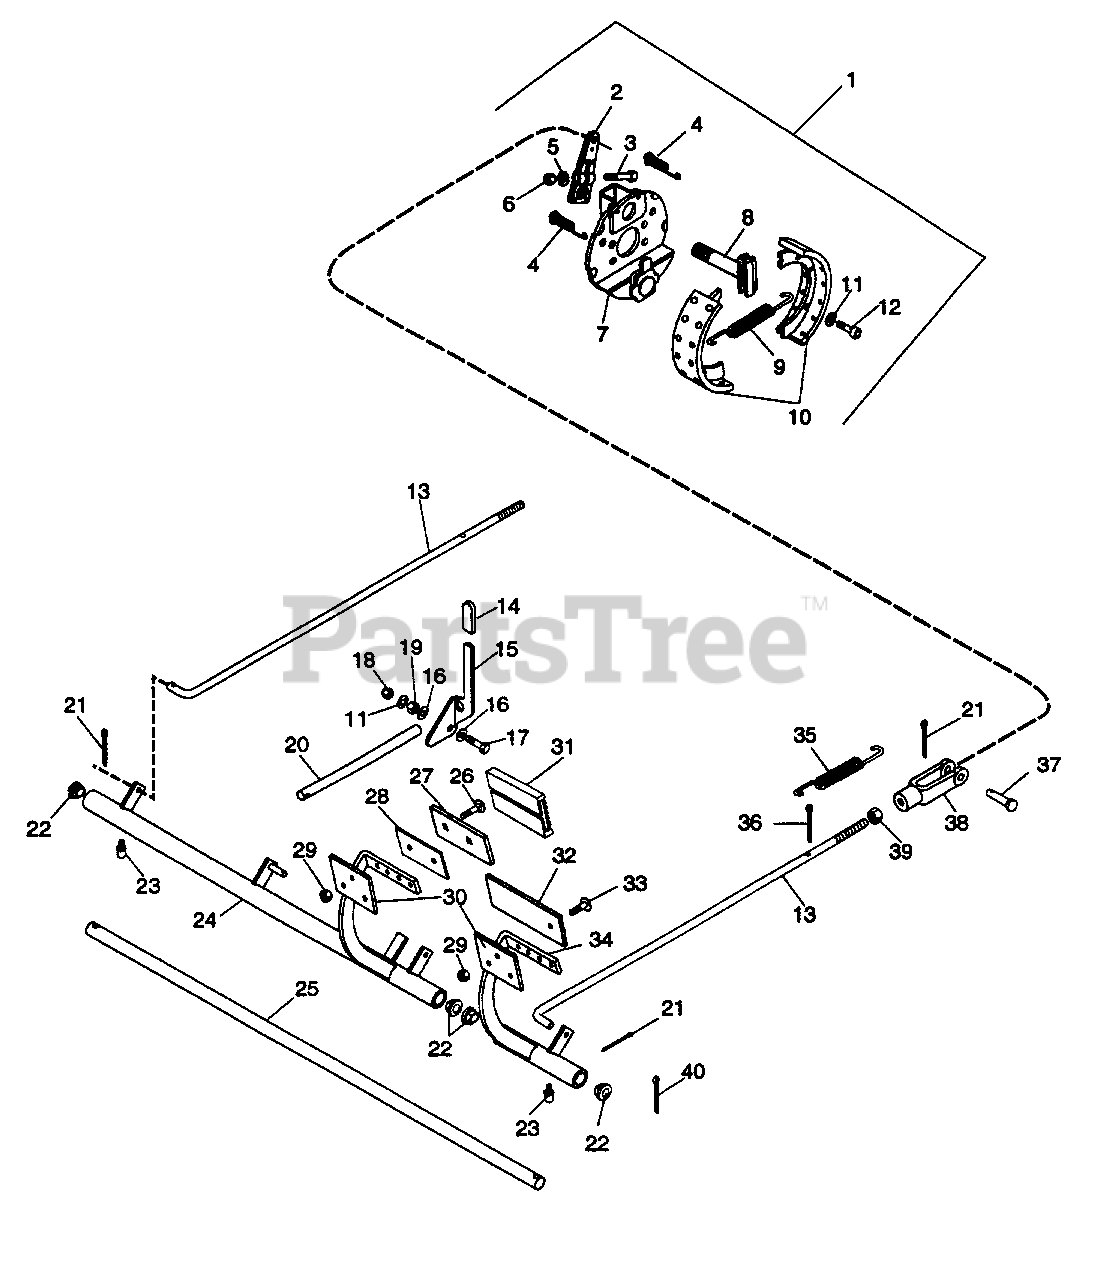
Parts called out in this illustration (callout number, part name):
1	BRAKE, 7 X 1.75 MECHANICAL
2	ARM, CAM LVR
3	BLT-HEX .31-24 X 1.75
4	SPRG, SHOE RET BOX
5	WSHR-LOCK .313 X .078 PL
6	NUT-HEX .312-24 ZC
7	PLT, BACK BENDIX #310949
8	CAM BRAKE
9	SPRG, SHOE RTN
10	KIT, BRK SHOE BEN 317974
11	WSHR-LOCK .375 X .094 MED PL
12	SCR-CAP .38-16 X 1.25
13	ROD, BRAKE
14	TIP - BRAKE LOCK LEVER
15	ARM, PARKING BRAKE LOCK
16	WSHR-FL-NY .375 X .75 X .060
17	BLT-HEX .38 - 16 X 1.38
18	NUT-LK-CTR .375-16 TYP N
19	NUT-HEX .375 - 16
20	ROD, BRAKE LOCK
21	PIN-COTR .09 X .75 PL
22	BSHG-FLG .630 X 1.000 X .625 NY
23	FTG, LUBE; .25-28 SELF-THREAD
24	WLDMT, BRAKE PEDAL
25	SHFT, BRAKE
26	BLT-CARRIAGE .25-20 X 1.25
27	PEDAL, BRAKE
28	PLT, BRAKE
29	NUT-LK-NYL .250-20 PL
30	PLT, BRAKE LOCK BACKING
31	PAD, PEDAL
32	ARM, BRAKE LOCK
33	SCR-MCH .25-20 X 1.00
34	WLDMT-BRAKE PEDAL
35	SG-TENS .091 X .500 X 5.500
36	PIN-COTR .12 X .75 PL
37	PIN-CLEVIS .375 X .948 ZC PL
38	CLVS, 3/8 - 24 ADJUSTABLE
39	NUT JAM .375 - 24 PL
40	PIN-COTR .12 X 1.25 PL
